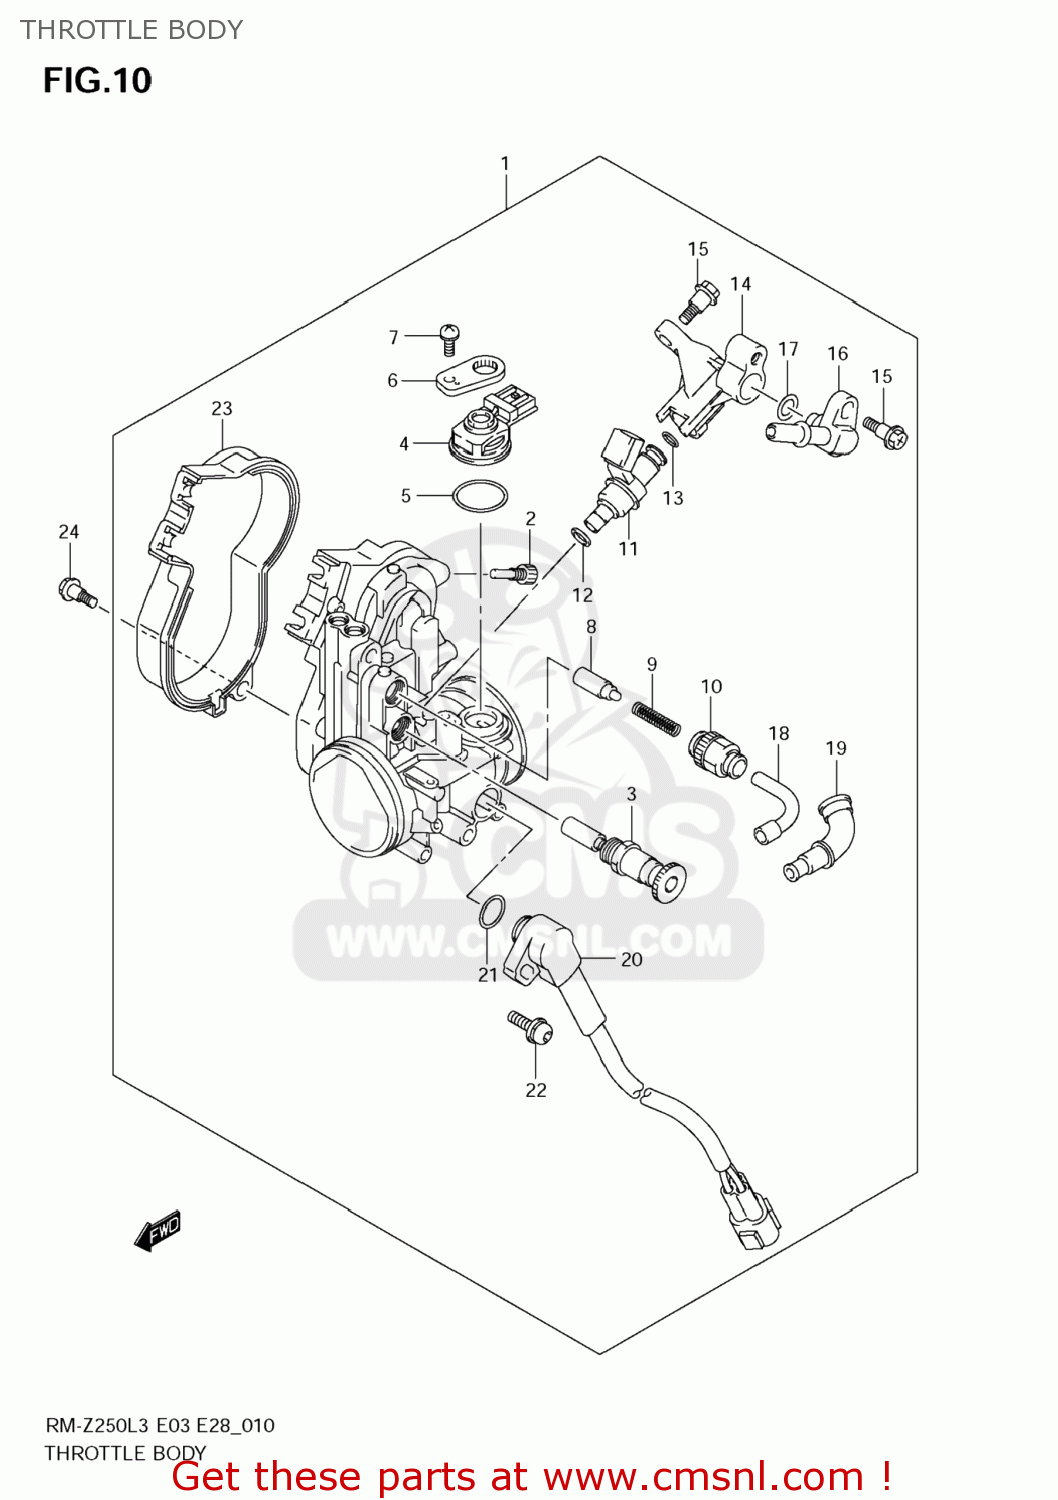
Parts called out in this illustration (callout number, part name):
1	BODY ASSY,THROTTLE
2	SCREW
3	STARTER
4	SENSOR,MAP
5	O RING
6	PLATE,STAY
7	SCREW
8	VALVE,STARTER
9	SPRING
10	HOLDER,CABLE
11	INJECTOR ASSY
12	RING,SEAL
13	O RING
14	PIPE,FUEL
15	SCREW
16	JOINT
17	O RING
18	GUIDE,CABLE
19	CAP
20	SENSOR ASSY,THROTTLE
21	O RING
22	SCREW
23	COVER,THROTTLE
24	SCREW
